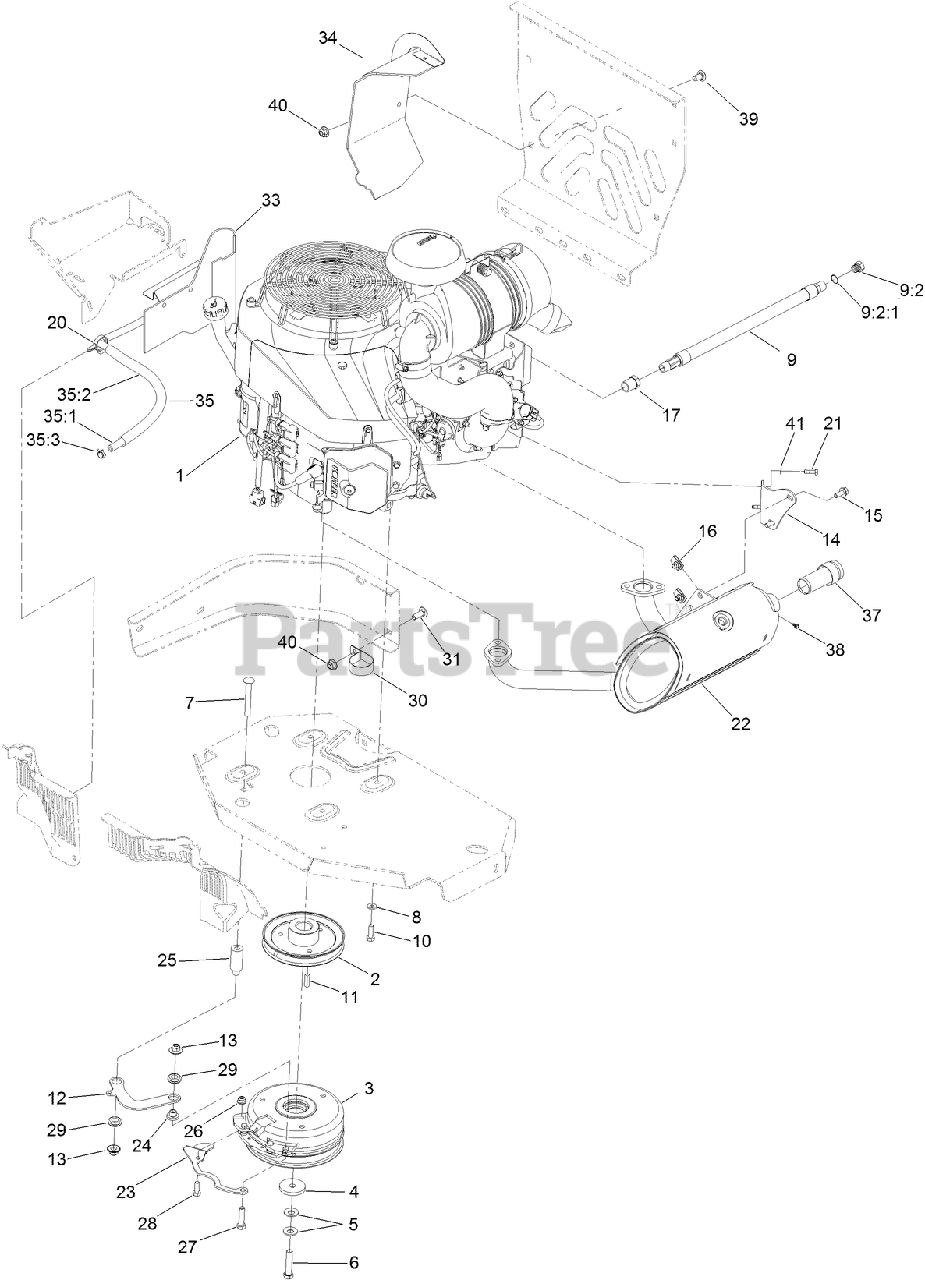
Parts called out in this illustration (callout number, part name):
1	ENGINE-KOHLER, ECV940 EFI-EGOV
2	SHEAVE
3	CLUTCH KIT
4	WASHER-CLUTCH
5	WASHER-SPRING
6	SCREW-HH
7	SCREW-CARR
8	WASHER-SPRING
9	OIL DRAIN HOSE ASM
9:2	PLUG-HH
9:2:1	O-RING
10	SCREW-HH
12	LINK-ANCHOR, CLUTCH
13	NUT-FLANGE, NI
14	Bracket-Muffler
15	SCREW-HHF
16	NUT-U
17	BUSHING
20	CLAMP-HOSE
21	SCREW-HH
22	MUFFLER
23	BELT-GUIDE
24	SPACER
25	SPACER
26	NUT-HF, NI
27	SCREW-HH
28	SCREW-HH
29	GROMMET-RUBBER
30	CLAMP-R
31	SCREW-CARR
33	BAFFLE-RH
34	BAFFLE-REAR
35	FUEL LINE ASM
35:1	HOSE-FUEL
35:2	SLEEVE-THERMAL
35:3	CLAMP-HOSE
37	ARRESTOR-SPARK
38	SCREW-HWH
39	SCREW-CARR
40	NUT-HF, NI
41	WASHER-SPRING
